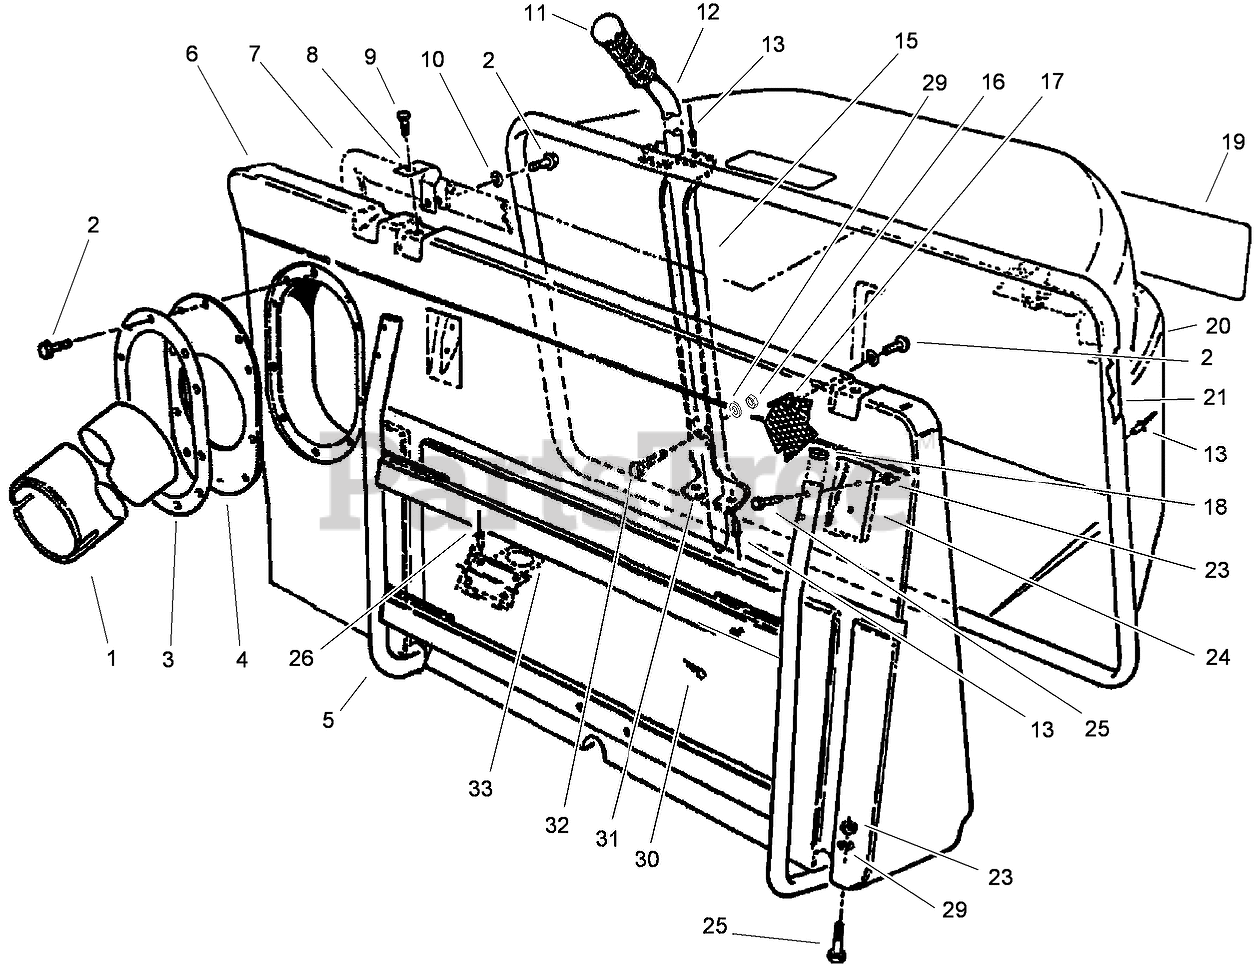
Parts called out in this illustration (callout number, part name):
1	DUCT-BAGGER
2	SCREW-HWHTF
3	RING-RETAINING
4	RING-RETAINER, RUBBER
6	BAG-FRONT
7	SEAL-BAG
8	BRACKET-HINGE
9	SCREW-HH
10	WASHER-FLAT
11	GRIP-HANDLE
12	HANDLE-DUMP
13	RIVET-POP
15	BRACKET-CHANNEL, DUMP HANDLE
16	NUT-LOCK, NI
17	SCREEN-BAG
19	DECAL-BAG, EASY EMPTY
20	BASKET-GRASS
21	FRAME-BASKET, GRASS
23	NUT-LOCK, NI
24	PLATE-BACKUP
25	SCREW-HH
26	RIVET-BLIND
29	WASHER-FLAT
30	PIN-HAIR
31	GUIDE-HANDLE, DUMP
32	SCREW-HH
